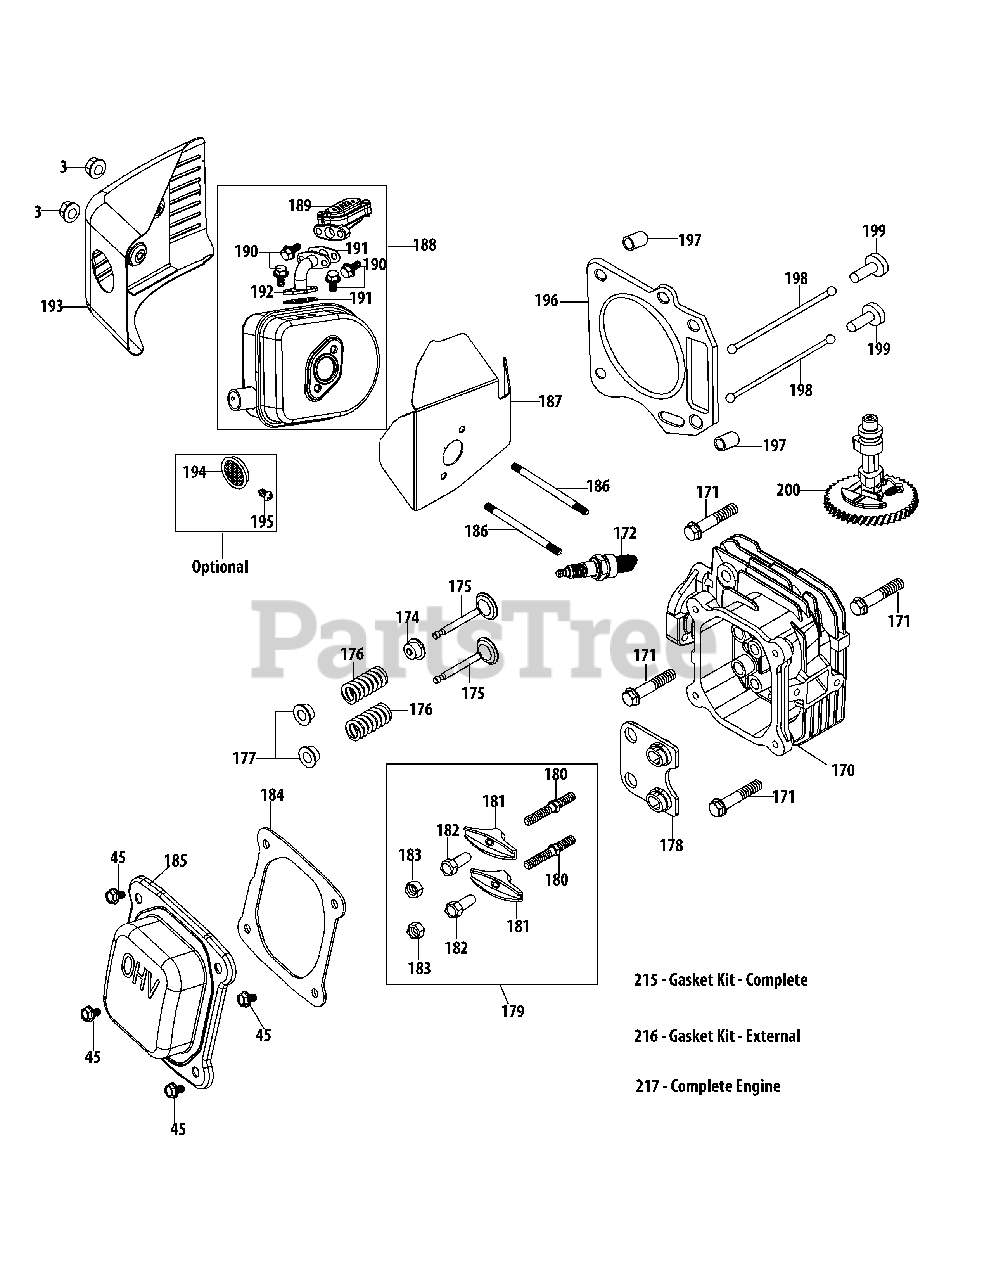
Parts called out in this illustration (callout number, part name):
3	Nut M6X10mm
45	Bolt M6X14
170	Cylinder Head Assembly
171	Bolt M8X54
172	Spark Plug
174	Intake Valve Seal
176	Valve Spring
177	Valve Spring Retainer
178	Push Rod Guide
179	Rocker Arm Assembly
180	Rocker Arm Stud
181	Rocker Arm
182	Fulcrum Nut
184	Valve Cover Gasket
185	Valve Cover
186	Muffler Stud M6X95
186	Muffler Stud Assemlby
187	Muffler Gasket
188	Muffler Assembly
189	Secondary Air Valve
190	Bolt M6×12
191	Secondary Air Valve Gasket
192	Secondary Air Tube
193	Muffler Shield
194	Spark Arrestor
195	Spark Arrestor Screw
196	Cylinder Head Gasket
197	Cylinder Head Dowel Pin 10×16
198	Push Rod Kit
200	Camshaft Assembly
215	Gasket Kit - Complete
216	Gasket Kit - External
217	Complete Engine
